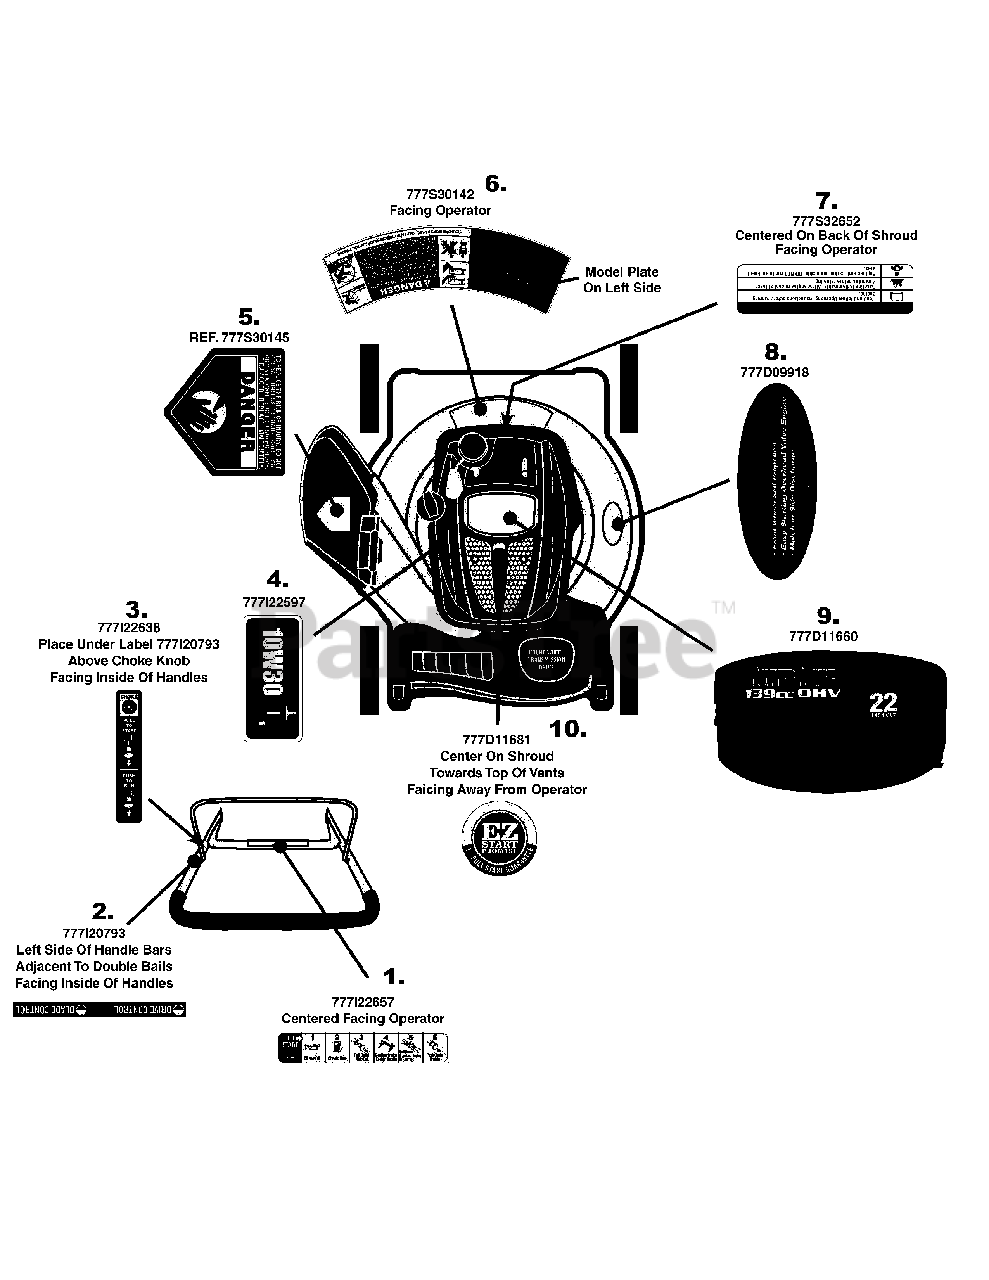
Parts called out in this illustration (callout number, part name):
1	LABEL-MOWER HANDLE
2	LABEL-HANDLE
3	LABEL-MOWER HANDLE:CHOKE START/RUN
4	LABEL:MOWER SHROUD
5	LABEL
6	LABEL-DANGER CURVE
7	LABEL:MOWER:ENGINE SHROUD
8	LABEL-MOWER DECK:YARDMAN
9	LABEL-MOWER SHROUD YARD MAN 22"
10	LABEL-MOWER SHROUD EZ START
